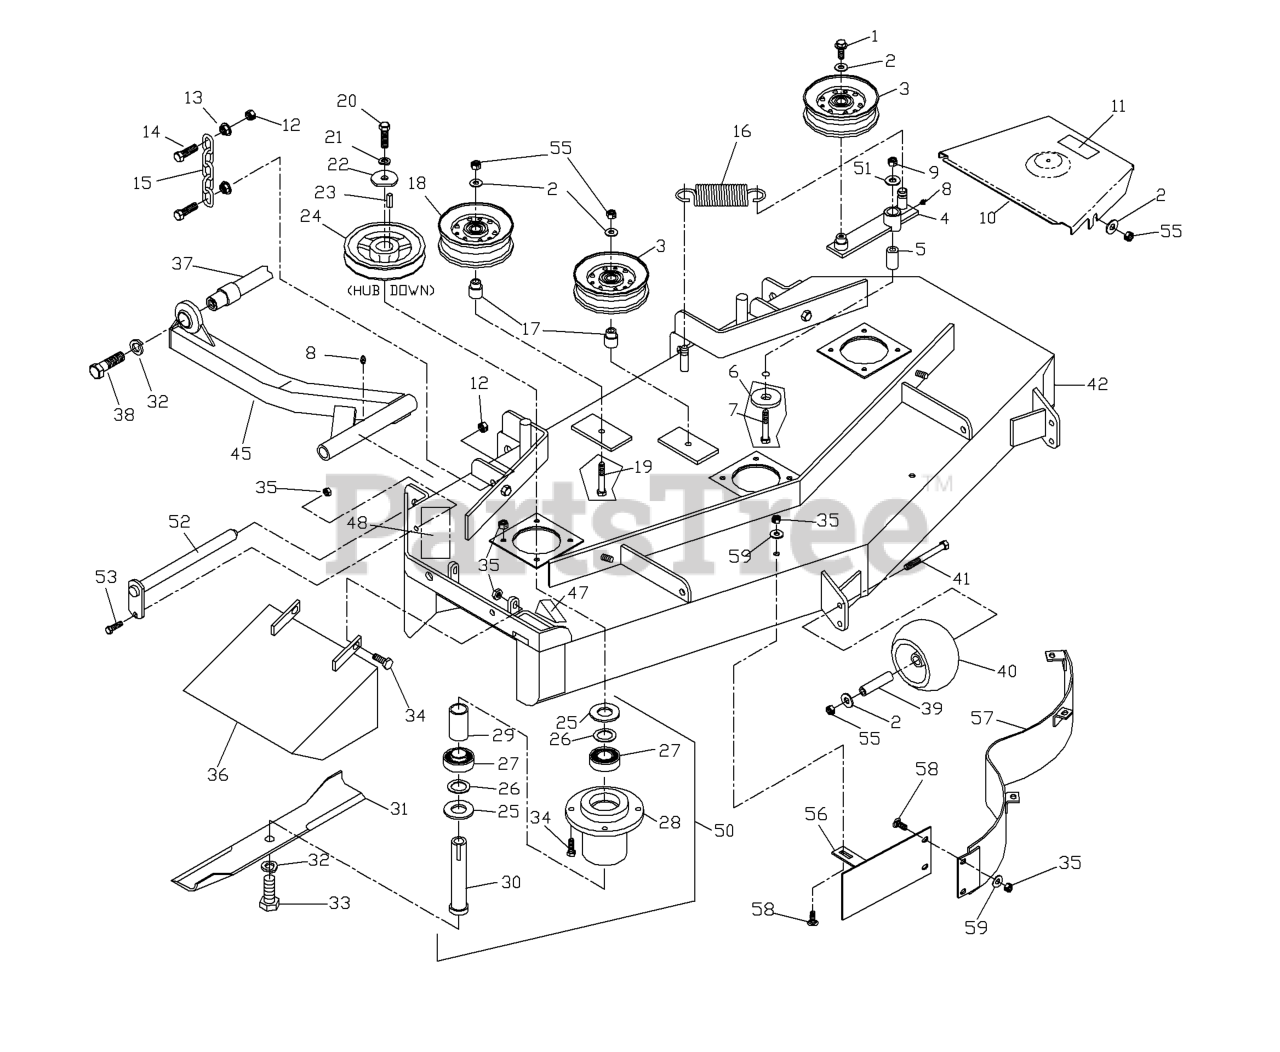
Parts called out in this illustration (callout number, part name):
1	4CS 3/8C X 1 SERRATED HEAD
2	WASHER 3/8 FLAT
3	IDLER PULLEY
5	PIVOT BUSHING
6	WASHER, SUPPORT
7	HCS 1/2C X 3 1/4
8	ZERK
9	NUT 1/2-13 HEX NYLOC ZD
10	BELTSHIELD
11	DECAL, NO STEP
12	NUT 7/16C CENTERLOCK
13	NUT 7/16C WHIZ
14	HCS 7/16C X 1 1/2
15	LIFT CHAIN
17	IDLER BUSHING
18	IDLER PULLEY (TALL)
19	HCS 3/8C X 2 1/2
20	HCS 7/16F X 1 1/2
21	WASHER 7/16 LOCK
22	SPINDLE WASHER
23	KEY 1/4 SQ X 1 1/8
25	MACHINERY BUSHING 10 GA.
26	BUSHING.MACHINE.18.GAUGE
27	BEARING
30	SPINDLE SHAFT
31	BLADE OEM 16 1/4"
32	LOCKWASHER 5/8
33	HCS 5/8F X 1 1/4
34	HCS 5/16C X 1
35	NUT 5/16C CENTERLOCK
36	DEFLECTOR CHUTE
37	STRUT MOUNT WELDMENT
38	HCS 5/8C X 2 GR.5
40	ANTI-SCALP ROLLER
41	HCS 3/8C X 3 1/2
42	DECK W/DECALS
45	STRUT WLDMT - RT
47	DECAL, CPSC
48	DECAL, DANGER
50	HOUSING, COMPLETE
51	WASHER 1/2 FLAT
53	HCS 5/16C X 3/4
55	NUT 3/8C CENTERBLOCK
56	CENTER BAFFLE 48"
57	MAIN BAFFLE - 48" DECK BLK
58	CARRIAGE BOLT 5/16C X 5/8"
59	WASHER 5/16 FLAT
